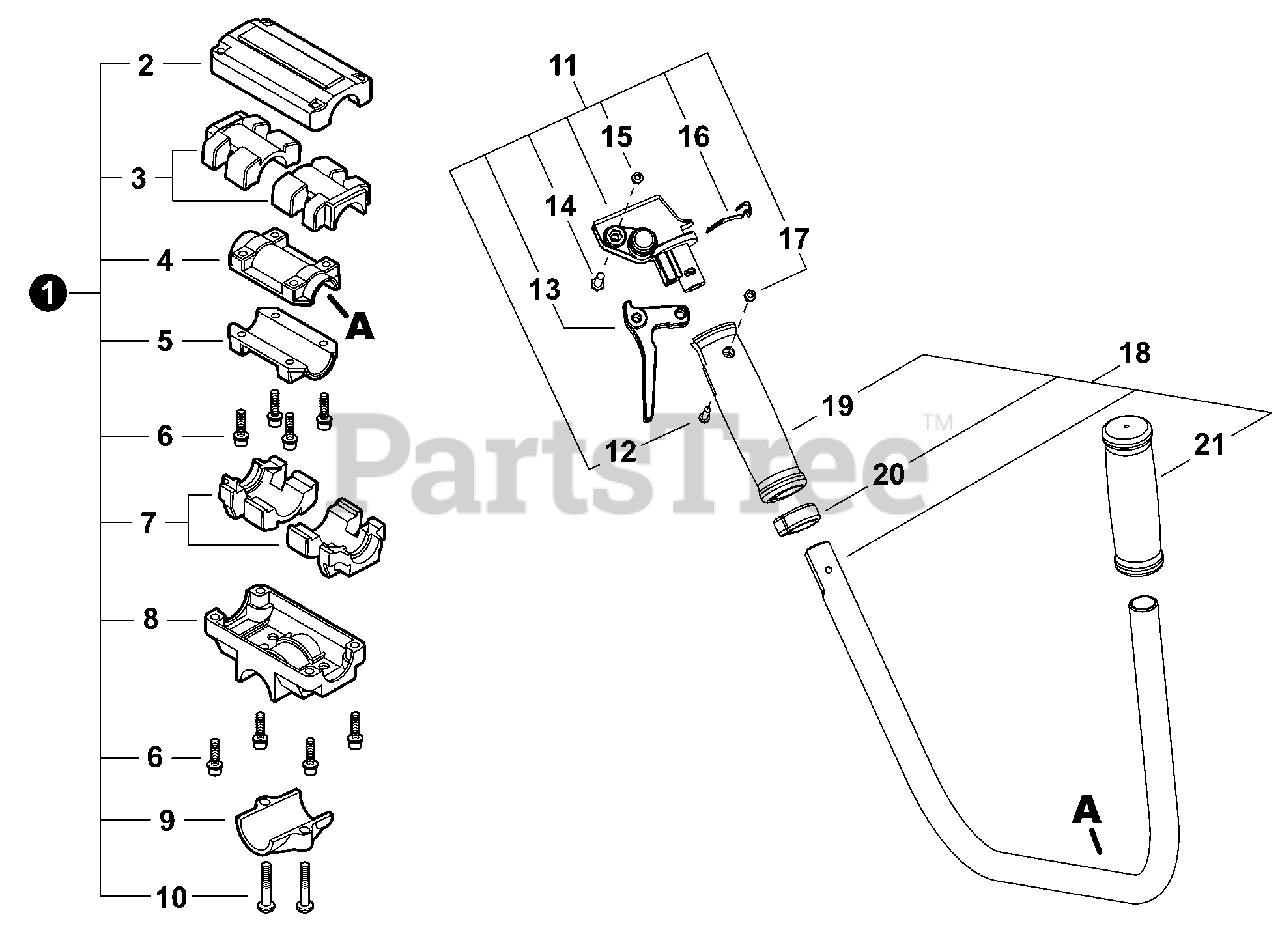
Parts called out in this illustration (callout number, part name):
1	BRACKET ASSY, HANDLEBAR
2	BRACKET, UPPER
3	CUSHION, UPPER
4	CLAMP, UPPER
5	CLAMP, LOWER
6	BOLT M5×25
7	CUSHION, LOWER
8	BRACKET, LOWER
9	BRACKET, MOUNTING
10	SCREW M6×25
11	THROTTLE CONTROL ASSY
12	BOLT M4×24
13	TRIGGER, THROTTLE
14	BOLT
15	NUT, LOCK M5
16	STOPPER, THROTTLE TRIGGER
17	NUT, NYLON M4
18	HANDLEBAR ASSY
19	GRIP, RIGHT
20	HOLDER, THROTTLE CABLE
21	GRIP, LEFT
